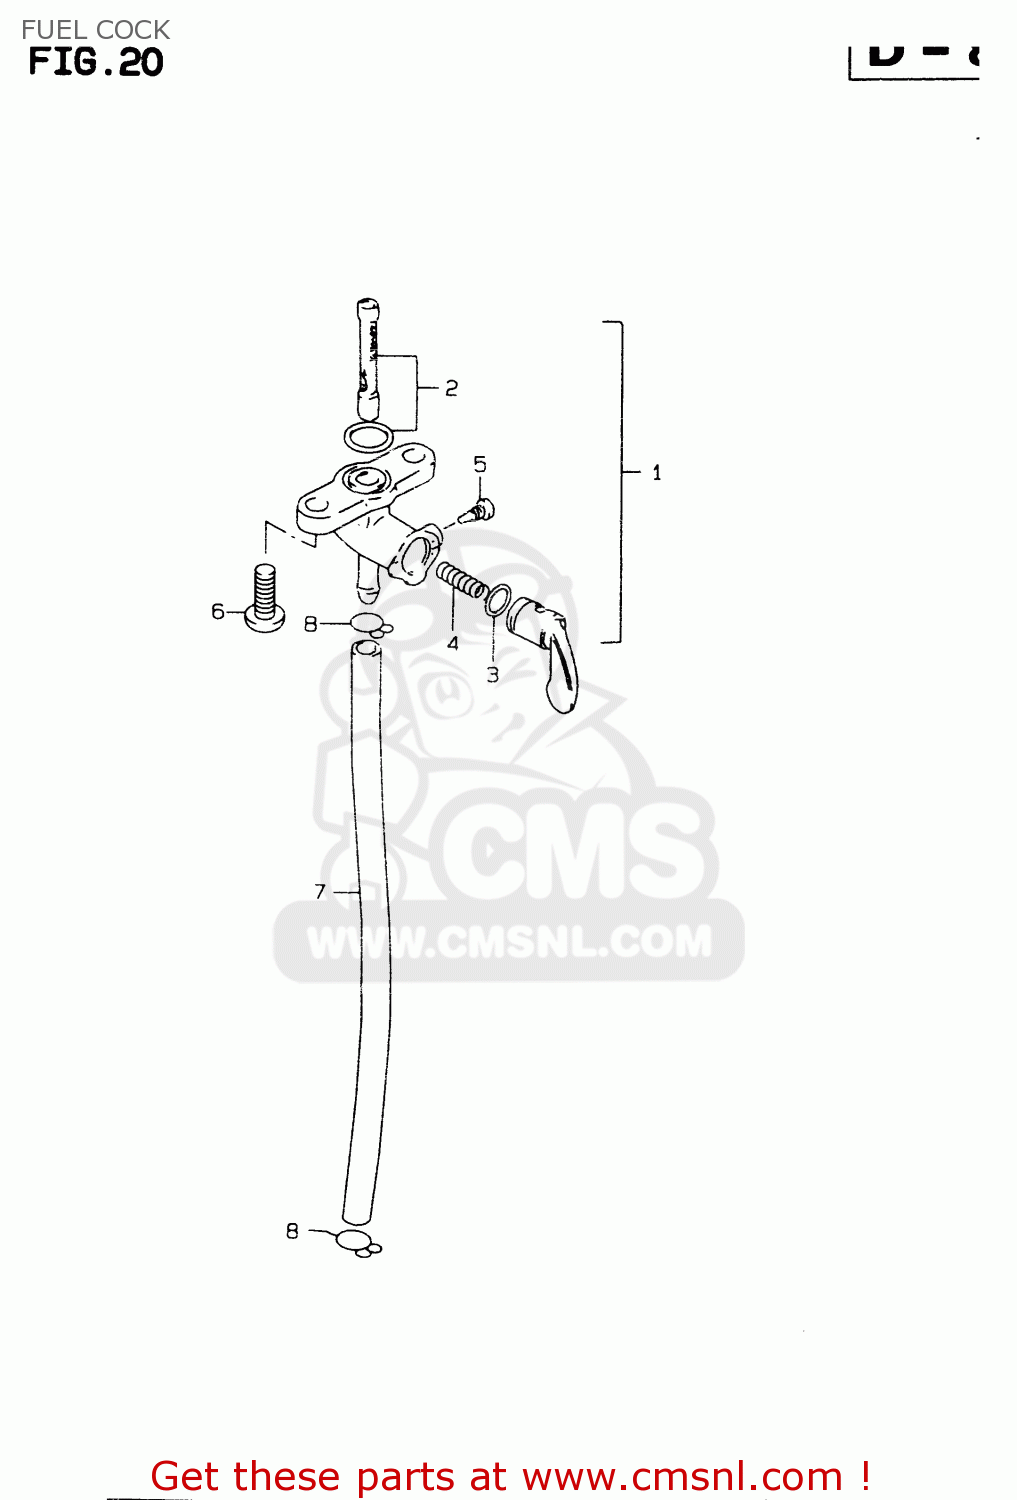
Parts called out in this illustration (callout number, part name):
1	COCK ASSY,FUEL
2	FILTER SET FUEL
3	O RING,LEVER
4	SPRING,FUEL COCK VALUE
5	SCREW
6	SCREW
7	HOSE(5X8.2X600)
8	CLIP
